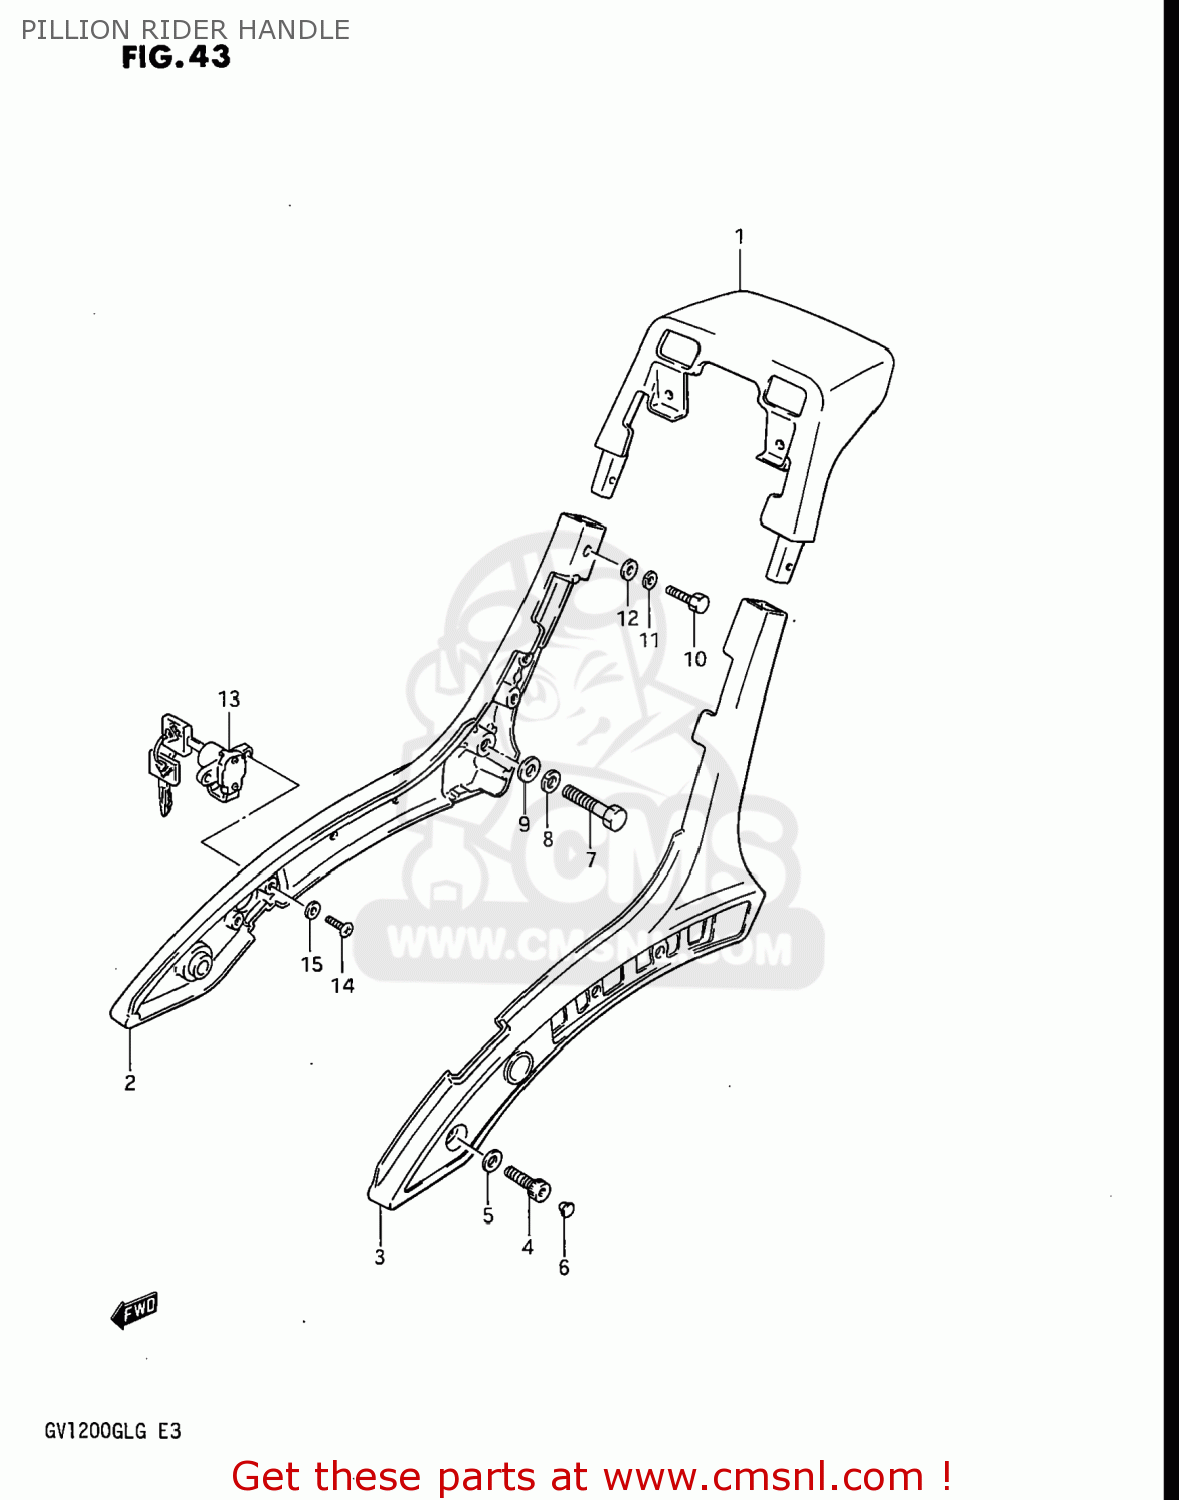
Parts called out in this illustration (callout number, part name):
1	HANDLE,PILLION RIDER U
2	HANDLE,PILLION RIDER,RIGHT
3	HANDLE,PILLION RIDER,LEFT
4	BOLT
5	WASHER
6	CAP(OD:14.5)
7	BOLT
8	LOCK WASHER
9	WASHER
10	BOLT,M6X1X20
11	WASHER,LOCK
12	WASHER, LOWER
13	LOCK SET,TAIL COVER
14	SCREW
15	WASHER,LOCK
